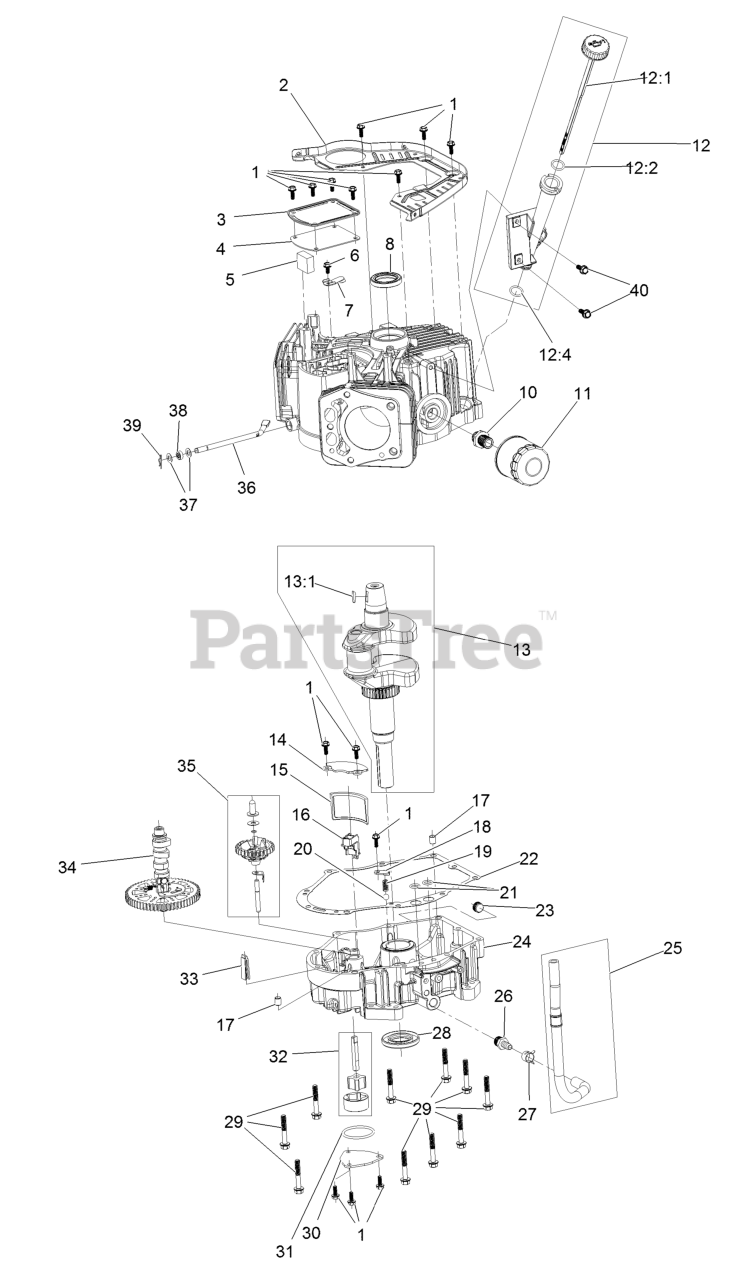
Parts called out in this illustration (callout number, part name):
1	Screw-HHF
3	Cover-Breather
4	Gasket-Breather
5	Filter-Breather
6	Screw-HHF
7	Valve-Breather
8	Seal-Oil
10	Adaptor-Filter, Oil
11	Filter-Oil
12	Oil Tube ASM
12:1	Dipstick
13	Crankshaft
13:1	Key-Woodruff
14	Cover-Screen, Oil
15	Screen-Oil
16	Retainer-Screen
17	Pin-Dowel
18	Plate-Retainer
20	Valve-Ball
22	Gasket-Cover, Crankcase
23	Plug-Drain
24	Cover-Crankcase
25	Oil Drain Hose ASM
26	Fitting-Hose
27	Clamp-Hose
29	Screw-HHF
30	Cover-Oil Pump
32	Oil Pump ASM
33	Deflector-Oil, Rubber
34	Camshaft
35	Governor ASM
36	Rod-Governor
37	Washer-Plain
38	Seal-Oil
39	Pin-Hair
40	Screw-HHF
